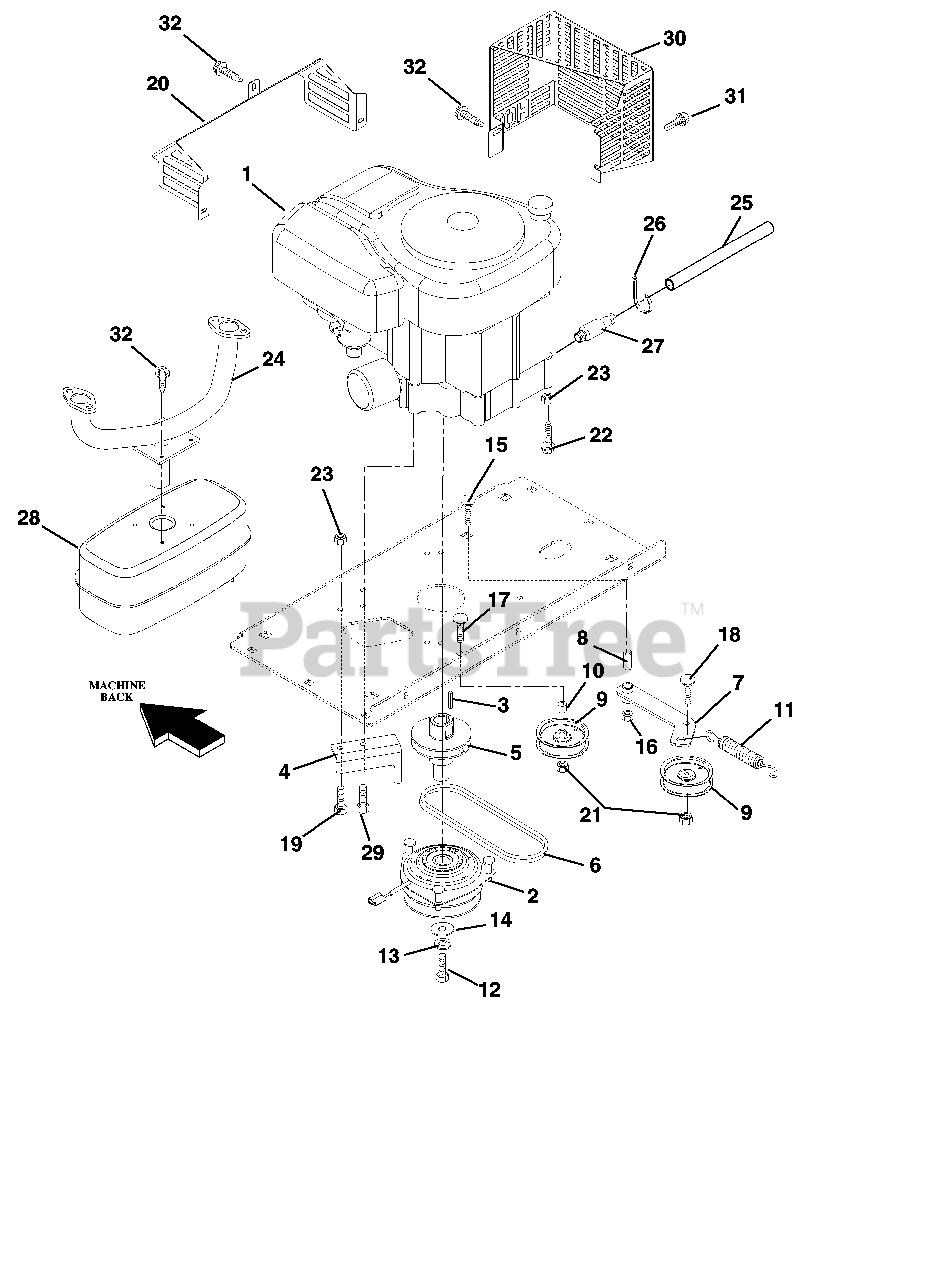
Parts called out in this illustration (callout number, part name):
1	ENGINE GROUP - 16HP
1	ENGINE GROUP - 18HP
1	ENGINE GROUP - 20HP
1	ENGINE GROUP - 22HP
2	CLUTCH, ELECTRIC
3	KEY-SQ .25 X 1.50 X .25 SAE
4	CLUTCH STOP
5	EXTENSION SHAFT
6	BELT,HA WRAPPED
7	IDLER-TRANSAXLE
8	BSHG-SLV .500X.750X1.560
9	PULLEY, IDLER 4.00
10	BSHG-SPCR .41X75X.69
11	SPRING, EXTENSION
12	BLT-HEX .44-20X4.50 GR8 YWZC
13	@WSHR-LK .44X.109 REG YWZC
14	WSHR-FL-STL .469X2.00X.25 YWZC
15	@BLT-HEX .50-13X2.50 GR5 YWZC
16	@NUT-LK-TOP-FLG .50-13 YWZC
17	BLT-RDHDSQNK .38-16X2.25 G5BZ
18	@BLT-RDHDSQNK .38-16X1.75 G5YZ
19	@BLT-HEX .31-18X.75 GR5 YWZC
20	MUFFLER GUARD, 40CI
21	NUT-LK-TOP-FLG .38-16 BLKZC
22	@BLT-HEX .31-18X1.50 GR5 YWZC
23	@NUT-LK-TOP-FLG .31-18 YWZC
24	PIPE, EXHAUST
25	TUBE, OIL DRAIN 8" CLEAR VINYL
26	CABLE TIE LG 5-1/2
27	VALVE, OIL DRAIN
28	MUFFLER - EXHAUST
29	@BLT-HEX .31-18X1.75 GR5 YWZC
30	MUFFLER GUARD, 31CI
31	BLT-SERHFWH .312-18X.50 YWZC
32	@SCR-TAP .25-20X.50 HWH TR YWZ
